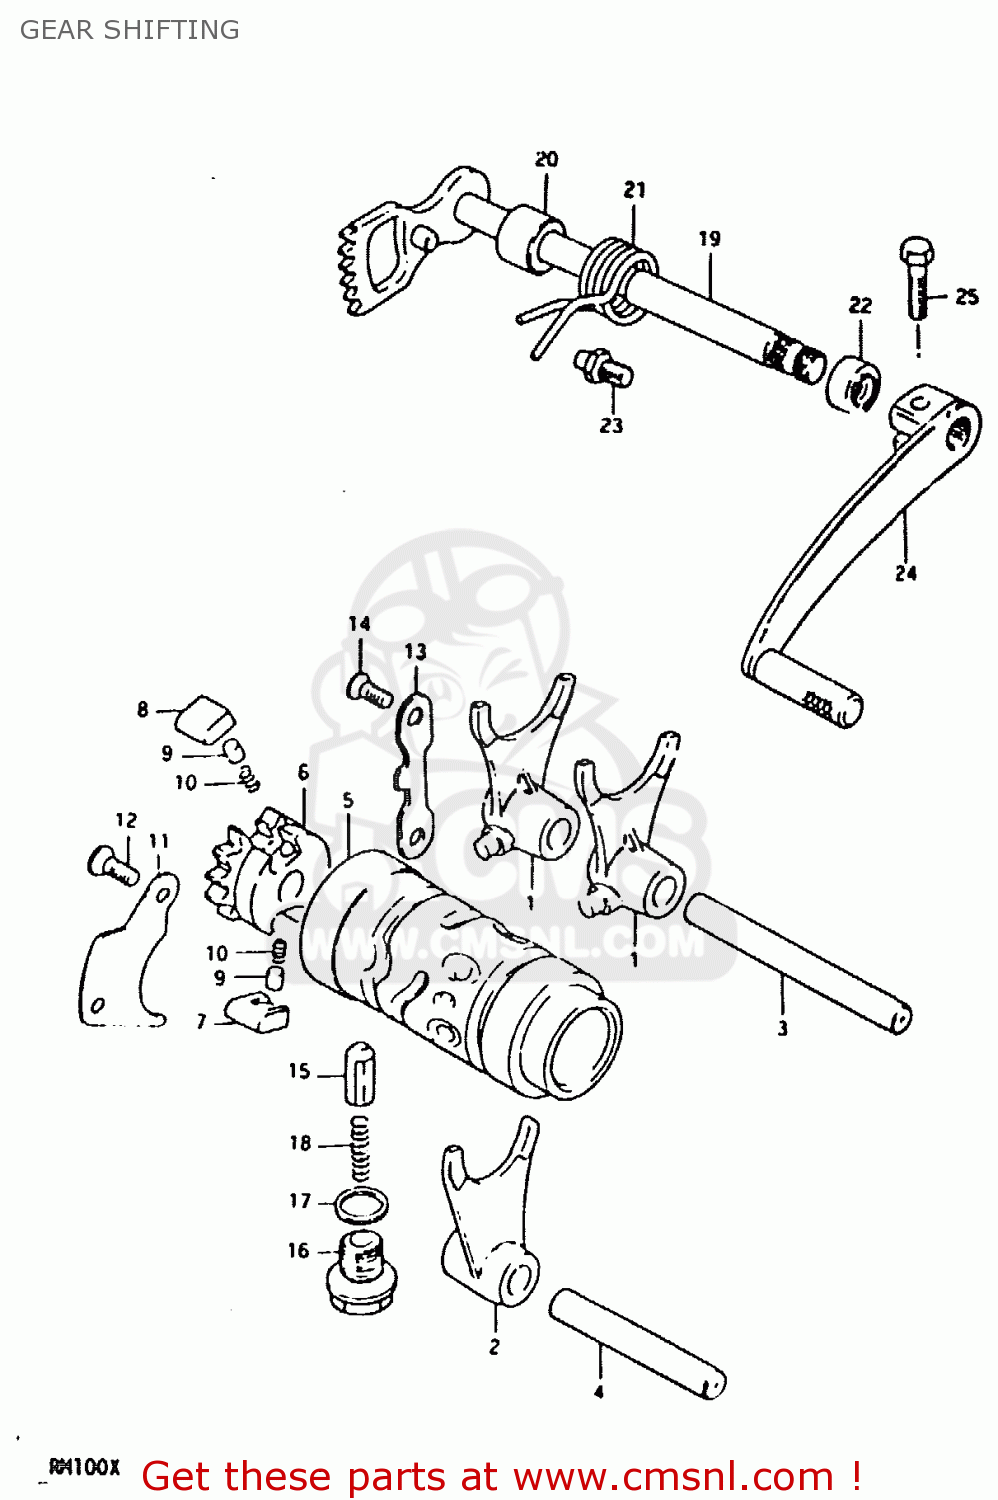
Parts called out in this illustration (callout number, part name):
1	FORK,GEAR SHIFT NO.1
2	FORK,GEAR SHIFT NO.2
3	SHAFT,GEAR SHIFT FORK
4	SHAFT,GEAR SHIFT FORK
5	CAM,GEAR SHIFT
6	RETAINER,GEAR SHIFT CAM
7	PAWL,GEAR SHIFT NO.1
8	PAWL,GEAR SHIFT NO.2
9	PIN(5X8)
10	SPRING
11	LIFTER,GEAR SHIFT PAWL
12	SCREW
13	GUIDE,GEAR SHIFT CAM
14	SCREW
15	STOPPER,GEAR SHIFTING
16	BOLT,GEAR SHAFT CAM STOPPER
17	GASKET(14X19.2X2) (NAS)
18	SPRING
19	SHAFT,GEAR SHIFT
20	SPACER(12X20X15.3)
21	SPRING
22	OIL SEAL
23	STOPPER,GEAR SHIFT CAM
24	LEVER ASSEMBLY,GEAR SHIFTING
25	BOLT
